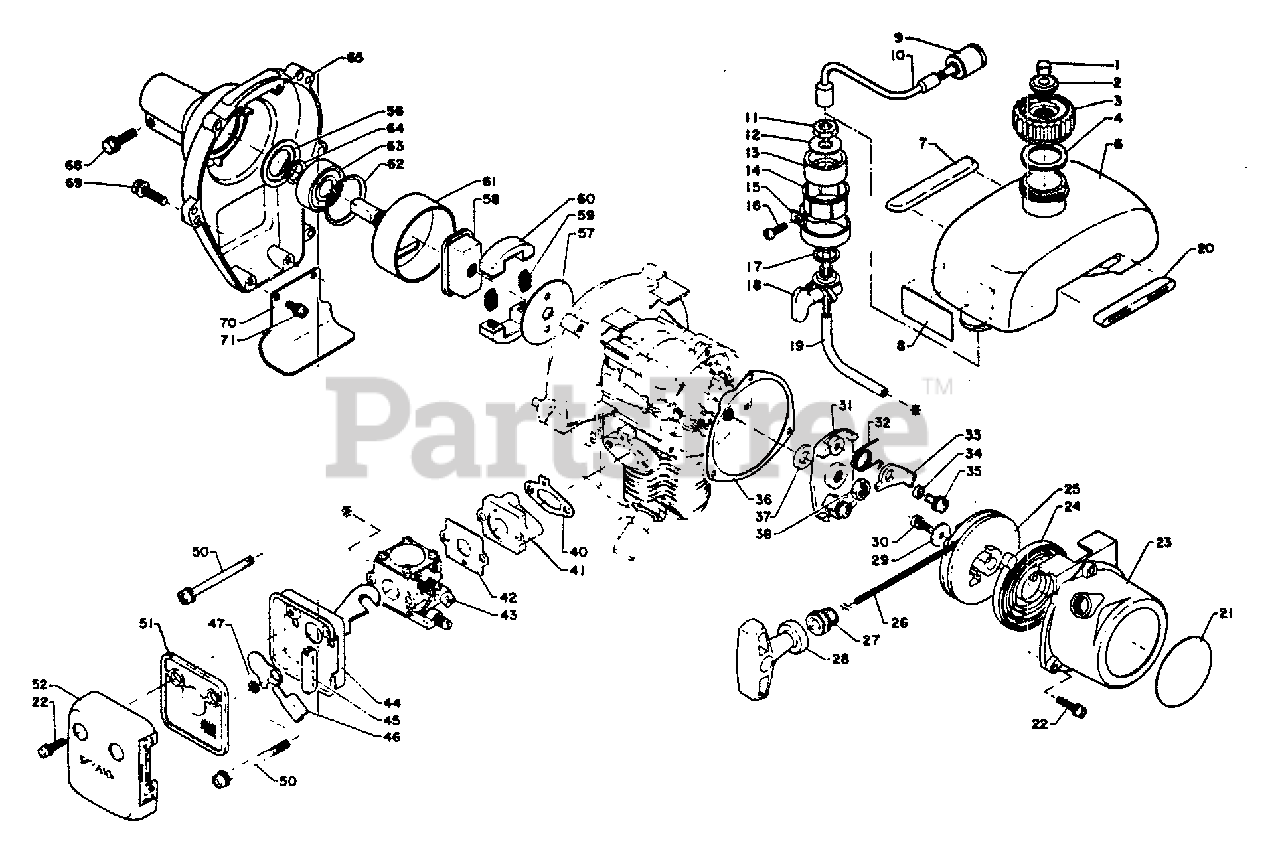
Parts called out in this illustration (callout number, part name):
3	CAP, FUEL
4	GASKET, CAP
6	TANK, FUEL
7	CUSHION
8	LABEL - FUEL VALVE
9	FILTER, FUEL
10	PIPE - FUEL
12	WASHER
13	SEAL
14	COLLAR
16	SCREW - 4X14
17	GASKET
18	FUEL VALVE ASSY
19	PIPE - 3X6X85 -- BLACK
20	CUSHION
21	PLATE, MODEL
22	SCREW - 4X20
23	CASE, STARTER
24	SPRING, REWIND
25	REEL, ROPE
26	ROPE, STARTER - 3X850
27	GUIDE, ROPE
28	GRIP, STARTER
30	SCREW - 4X10
31	CATCHER, PAWL
32	SPRING, RETURN
33	PAWL, STARTER
35	SCREW - 5X10
36	GASKET, STARTER
38	NUT - LEFT HAND
40	GASKET, INTAKE
41	INSULATOR, INTAKE
42	GASKET, INTAKE
43	CARBURETOR
44	CASE, AIR FILTER
46	SHUTTER, CHOKE
47	WASHER - 5
50	SCREW - 5X57
51	FILTER, AIR
52	COVER, AIR FILTER
56	RETAINER, PIPE
57	PLATE, CLUTCH
58	HUB, CLUTCH
59	SPRING, CLUTCH
60	SHOE, CLUTCH
61	DRUM, CLUTCH
62	RING, RETAINING - 32
63	BEARING, BALL - 6201
64	RING, RETAINING - 12
65	CASE, FAN
68	BOLT - 5X20
69	SCREW - 5X20
70	BRACKET
71	SCREW - 4X10
